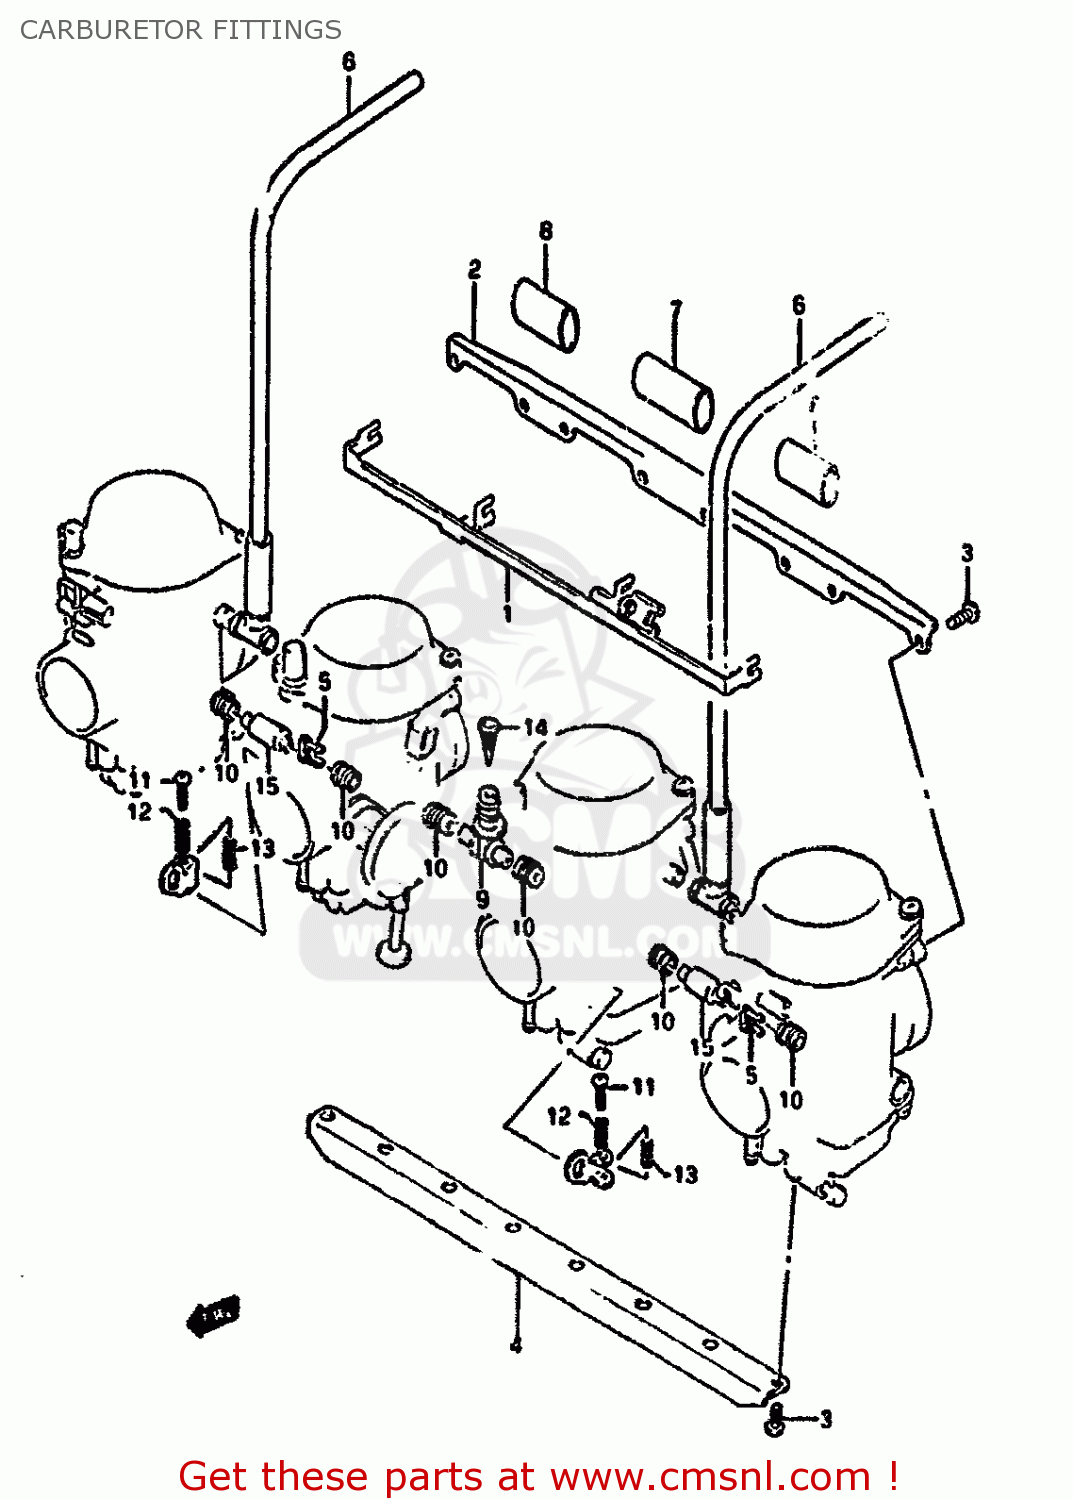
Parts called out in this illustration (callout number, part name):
1	LEVER
2	PLATE
3	SCREW
4	PLATE
5	HOLDER
6	HOSE
7	HOSE
8	HOSE
9	NIPPLE
10	SEAL
11	SCREW
12	SPRING
13	SPRING
14	FILTER
15	PIPE
